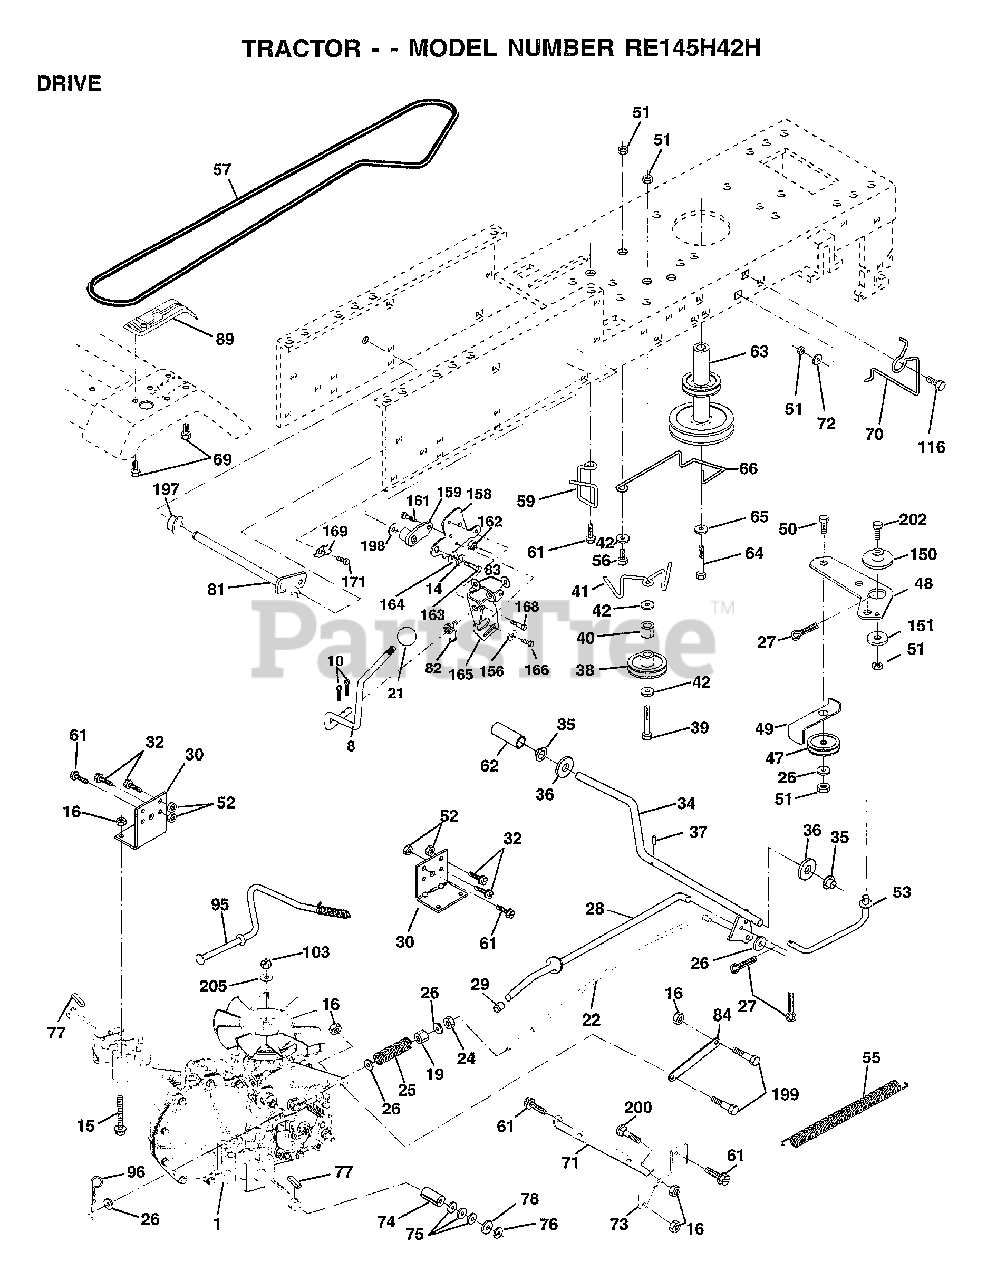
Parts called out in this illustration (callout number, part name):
8	ROD.SHIFT.FENDER.ADJ.LT.CRD
10	PIN COTTER 1/8
14	LOCKWASHER
15	BOLT.HX.FLG.5/16
16	NUT
19	NUT
21	KNOB T (1/2-HOLE)
22	ROD BRAKE HYDRO
24	NUT
25	SPRING ROD LT
26	WASHER
27	COTTER PIN
28	ROD.BRAKE.PARK.LT
29	PLUNGER CAP T
30	TRANSAXLE MTG BKT
32	BOLT
34	SHAFT ASM-PEDAL F
35	NYLON BEARING
36	WASHER LT
38	FLAT IDLER PULLEY
39	BOLT
40	SPACER T
41	"KEEPER,BELT.IDLER FLAT"
42	WASHER
48	BELLCRANK.CLUTCH
49	RETAIN BELT
53	"LINK, CLUTCH T"
55	"SPRING, RETURN LT"
57	"BELT.GD DRV 82"""
59	KEEPER BELT SPAN CTR
61	SCREW
62	PEDAL COVER T
63	PULLEY.ENGINE
64	BOLT
65	LOCKWASHER
66	KEEPER-BELT
69	SCREW HEXWSH H-L
70	KEEPER BELT ENG
71	STRAP TORQUE LH HYDRO
72	WASHER
73	STRAP TORQUE RH HYDRO
74	SPACER
75	WASHER
76	E-RING LT
77	SQUARE KEY
78	WASHER
81	SHAFT
82	"SPRING,TORSION"
83	WASHER
84	LINK TRANSAXLE
89	CONSOLE HYDRO
95	CONTROL ASSY
96	RETAINER M
116	BOLT RDHD 3/8-16
150	BUSHING.BELLCRANK.GRD.DR
151	WASHER
156	WASHER.SRRTD.5/16
158	BRKT.SHIFT.MOUNT
159	HUB.SHIFT
161	BOLT T
164	WASHER.5/8X.281X10GA
165	BRKT.PIVOT.LEVER
166	SCREW.5/16-18X5/8
168	BOLT.SHOULDER.5/16-18X.561
169	PLATE.FASTENING
171	SCREW LT
197	NYLINER SNAP-IN
198	WASHER NYLINER
199	BOLT SHOULDER
200	BOLT
202	BOLT.3/8-16X1.50
